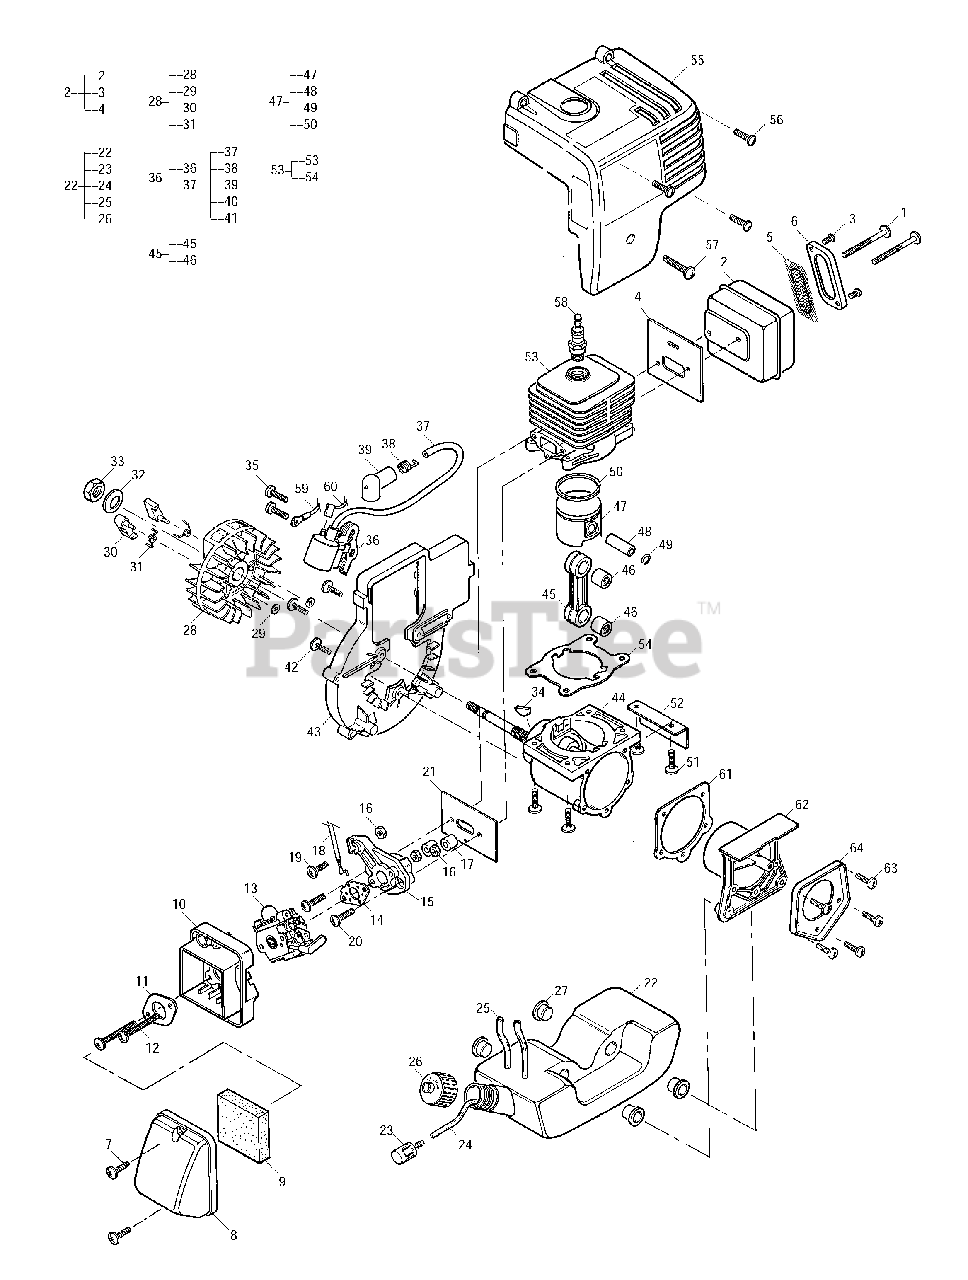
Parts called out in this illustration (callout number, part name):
1	Screw, 10-24x2.25 Taptite
2	Kit, Muffler
3	Screw
4	Plate, Muffler
5	Screen, Spark Arrester
6	Cover, Spark Arrester
7	Screw, 8-16 x .75 Tr Hd Plastite
8	Cover, Air Box
9	Filter, Air
10	Box, Air Filter
11	Plate, Air Box
12	Screw, 10-24 x 2 Torx
13	Carburetor Assembly
14	Gasket, Carburetor
15	Manifold, Carburetor
16	Nut, 10-24
17	Spacer, Rubber
18	Cable, Throttle
19	Screw, 10-24 x .62 Tr Hd Torx
20	Screw, 10-24 x .875 Taptite
21	Gasket, Manifold
22	Fuel Tank Asy
23	Filter, Fuel
24	Hose, Fuel
25	Hose, Fuel Return
26	Kit, Fuel Cap w/Retainer
27	Isolator, Fuel Tank
28	Flywheel Asy
29	Pawl Kit
29	Retainer Ring
30	Pawl, Starter
31	Spring, Starter Pawl
32	Washer, Conical Spring
34	Key, Flywheel
35	Screw, 10-24 x .875 Taptite
36	Ignition Asy
37	Kit, Spark Plug Wire
38	Connector, Spark
39	Boot, Spark Plug
42	Screw, 10-24 x .63
43	Shroud, Engine
44	Short Block Asy
45	Connecting Rod Asy
48	Piston Pin, C'shaft
49	Ring, Retaining
50	Ring, Piston
51	Screw, 10-24 x .688 Tri Rnd
52	Shield, Muffler
54	Gasket, Cylinder
55	Cover, Cylinder/Muffler
56	Screw, 8-16 x .75 Tr Hd Plastite
57	Screw, 10-14 x .75 Torx
58	Spark Plug, RDJ8J
59	Wire Asy, Ground
60	Wire Asy, Stop Switch
61	Gasket, C'case
62	Plug, C'case
63	Screw, 10-24 x .688 Tri Rnd
64	Plate, C'case
